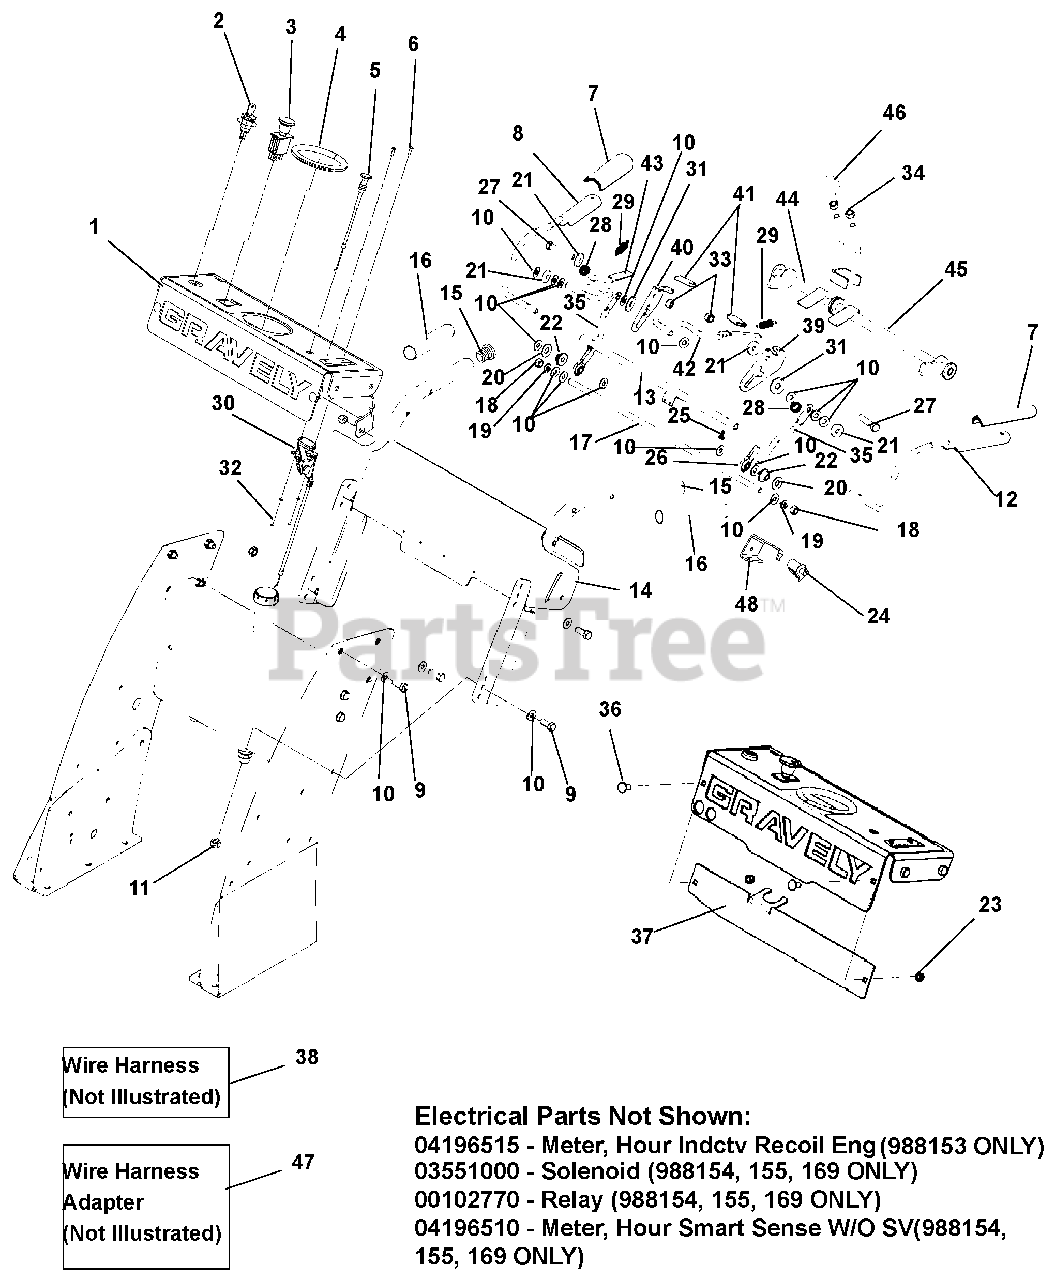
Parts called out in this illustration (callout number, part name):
1	ASSM, HYDRO WALK CONSOLE W/DECALS (SN 000101 - 020000)
1	ASSM, PG UPPER CON W/DECAL GRV (988153) (SN 020001 and up)
1	ASSM, UPPER CON, 48/52/61 RED (988154, 155, 169) (SN 020001 and up)
2	SWITCH, TWO POSITION KEY (988153)
2	SWITCH, THREE POSITION KEY (988154, 155, 169)
3	SWITCH, CLUTCH w/GRAPHIC
4	TRIM, RUBBER EDGE 12"
5	CABLE, CHOKE 48" (SN 000101 - 020000)
5	CABLE, CHOKE 43" (988153) (SN 020001 and up)
5	CABLE, CHOKE (988154, 155, 169) (SN 020001 and up)
6	SCR-PANHDSLT 8-32X.50 YWZC (SN 000101 - 020000)
6	SCR-PANHDSLT 8-32X.50 YWZC (988153) (SN 020001 and up)
6	SCREW-MACHINE 10-24X.75 HEX WASHER HEAD (988154, 155, 169) (SN 020001 and up)
7	GRIP, CLUTCH LEVER, LH AND RH
8	WMT-RH LEVER-OP
9	BOLT, HEX .38-16 X 1.00 GR5 Y
10	WASHER, .406 X .813 X .065 FLAT Y
11	LOCKNUT, .38-16 NYLOC Y
12	WMT-LH LEVER-OP
13	WMT-PIVOT TUBE
14	GRAVELY PG HYDRO W/DECALS (SN 000101 - 020000)
14	CONSOLE, LOWER PG CE W/DECAL (SN 020001 and up)
15	CAPLUG, HANDLEBAR
16	GRIP, HANDLEBAR
17	ROD, SPEED CONTROL
18	NUT-HEX .375-24 YWZC GR2
19	WASHER-LOCK .38 X .094 REG
20	WASHER-FLAT-NYL .52 X 1.00 X .08
21	WASHER-FLAT-STL .406 X 1.00 X .188
22	BUSHING-FLANG .385 X .500 X .875 X .31
23	NUT-LOCKING-NYLON .312-18
24	SWITCH, SEAT OVER RIDE (N.O.)
25	SCREW-TAP 10-24 X .50 HWH
26	ROD END, .38 RH
27	BOLT - HEX .38-16 X 2.00 GR5
28	SPRING-COMPRESSION .045 X .600 X .750
29	SPRING-TENSION .041 X .500 X 1.750
30	CABLE, THROTTLE - 49.5 (SN 000101 - 020000)
30	CABLE, THROTTLE 43" (988153) (SN 020001 and up)
30	CABLE, THROTTLE 49.5" (988154, 155, 169) (SN 020001 and up)
31	WASHER-FLAT-STEEL .50 X 1.25 X .083
32	NUT-LK-NYL 8-32 W/INSTR YWZC (SN 000101 - 020000)
32	NUT-LK-NYL 8-32 W/INSTR YWZC (988154, 155, 169) (SN 020001 and up)
32	NUT-LK-NYL 10-24 W/INSRT (988153) (SN 020001 and up)
33	NUT-LK-CTR .375-16
34	NUT-HEX .38-16
35	ROD, STEERING LINK
36	BOLT-RDHDSQNK .31-18X.75 G5
37	BRACKET, REMOTE ROV HYDRO (SN 000101 - 010000)
37	BRACKET, REMOTE ROV HYDRO (SN 010001 and up)
39	LATCH-LH THUMB
40	LATCH-RH THUMB
41	GRIP, THUMB LATCH
42	LEVER, HAND CONTROL LH
43	LEVER, HAND CONTROL RH
44	WELDMENT, RH LEVER
45	WELDMENT, LH LEVER
46	KNOB,BALL -BLACK 1.47" .375-16
48	BRKT, OPC SWITCH
